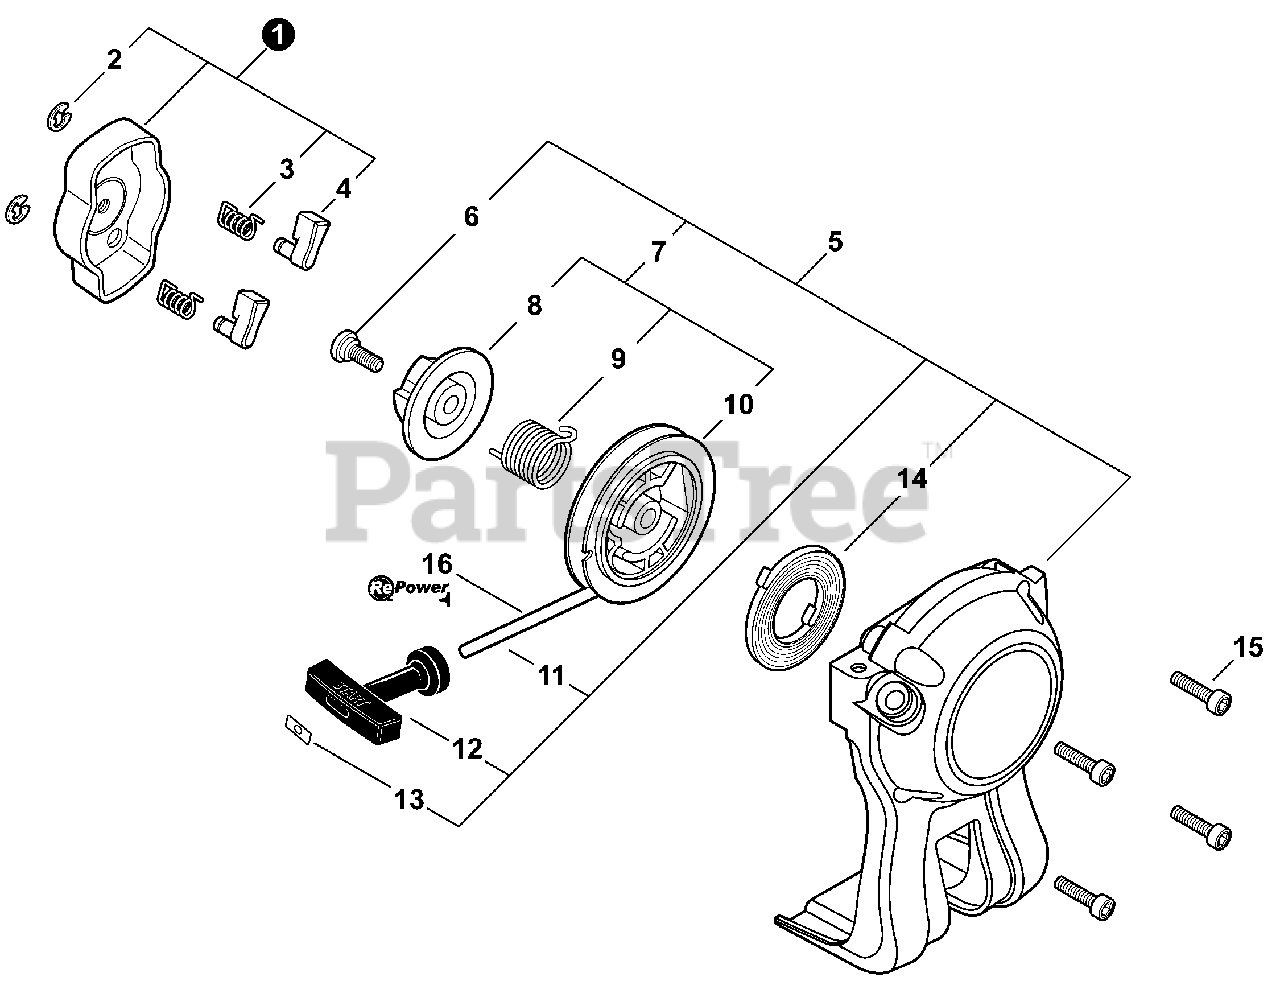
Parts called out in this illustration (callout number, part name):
1	PAWL ASSY, STARTER
2	E-RING 4
3	SPRING, RETURN
4	PAWL, STARTER
5	STARTER ASSY, RECOIL
6	SCREW
7	REEL KIT, ROPE
8	PLATE, CAM
9	SPRING, TORSION
10	REEL, ROPE
11	ROPE, STARTER
12	GRIP, STARTER
13	RETAINER, ROPE
14	SPRING, RECOIL
15	BOLT, TORX 4×16
16	ROPE, STARTER - REPOWER BULK 3
